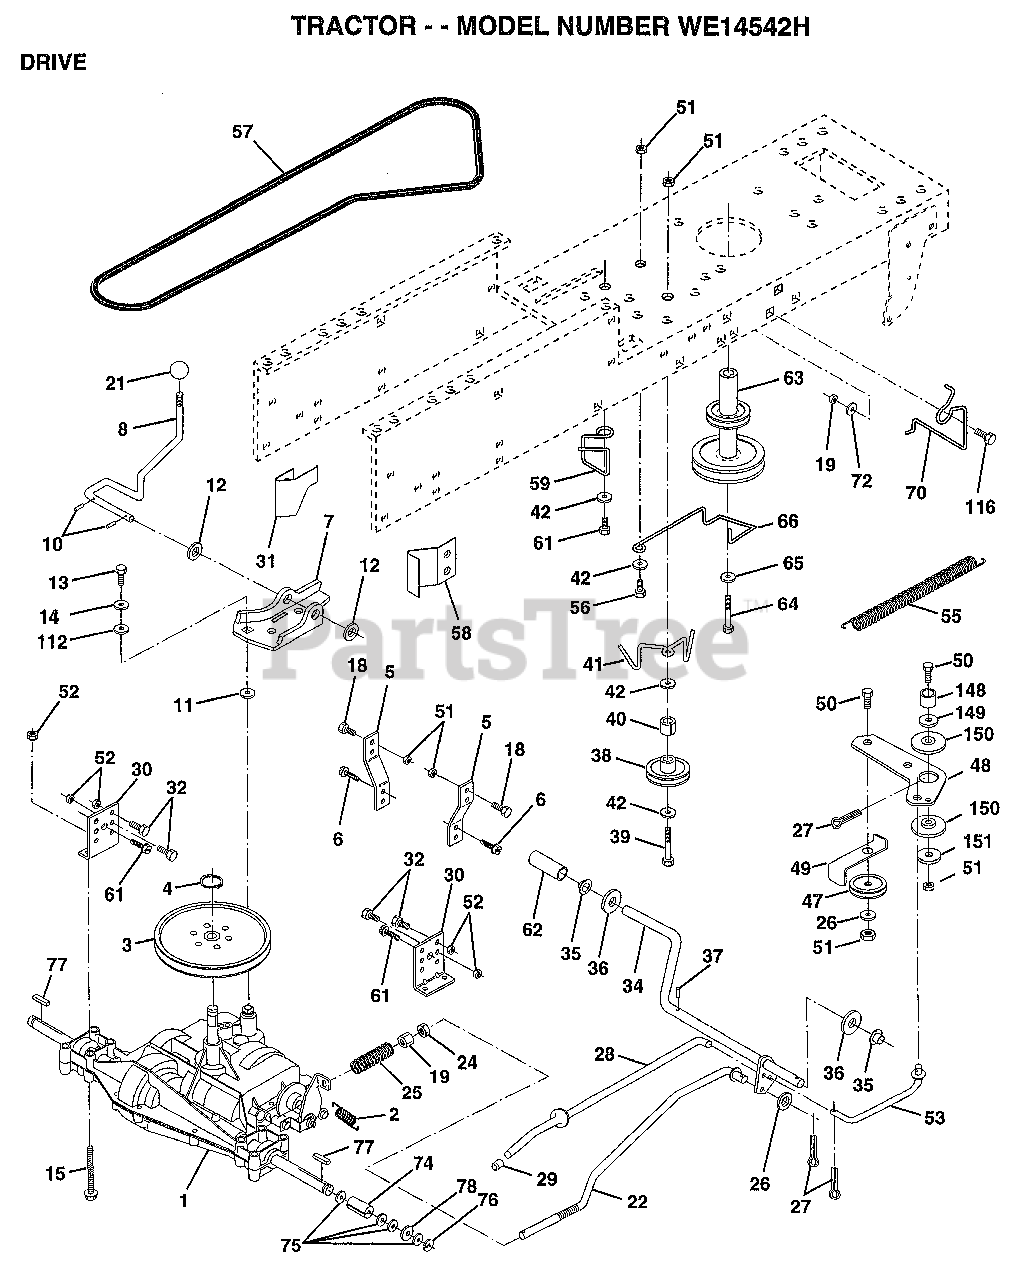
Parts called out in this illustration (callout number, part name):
2	SPRING.BRAKE.RETU
3	PULLEY TRANS
5	STRAP TORQUE
6	SCREW
7	BRKT.SADDLE.SHIFT
8	SHIFT ROD
10	PIN COTTER 1/8
11	WASH-SHFT PLT LT
12	WASHER
13	BOLT.1/4-28.W/PAT
14	LOCKWASHER
15	BOLT.HX.FLG.5/16
18	BOLT
19	NUT
21	KNOB T (1/2-HOLE)
22	BRAKE ROD
24	NUT
25	SPRING ROD LT
26	WASHER
27	COTTER PIN
28	ROD.BRAKE.PARK.LT
29	PLUNGER CAP T
30	TRANSAXLE MTG BKT
31	"KEEPER,BELT LH T"
32	BOLT
34	SHAFT ASM-PEDAL F
35	NYLON BEARING
36	WASHER LT
38	PULLEY.IDLER.FLAT
39	BOLT
40	SPACER T
42	WASHER
48	BELLCRANK.CLUTCH
49	RETAIN BELT
53	"LINK, CLUTCH T"
55	"SPRING, RETURN LT"
57	"V-BELT,95.3"
58	"KEEPER,BELT RH T"
59	KEEPER BELT CNTSP
61	SCREW
62	PEDAL COVER T
63	PULLEY.ENGINE
64	BOLT
65	LOCKWASHER
66	KEEPER-BELT
70	KEEPER BELT ENG
72	WASHER
74	SPACER LT
76	E-RING LT
77	SQUARE KEY
78	WASHER
112	WASHER LT
116	BOLT RDHD 3/8-16
149	SPACER RETAINER
150	BUSHING.NYLON
151	WASHER
